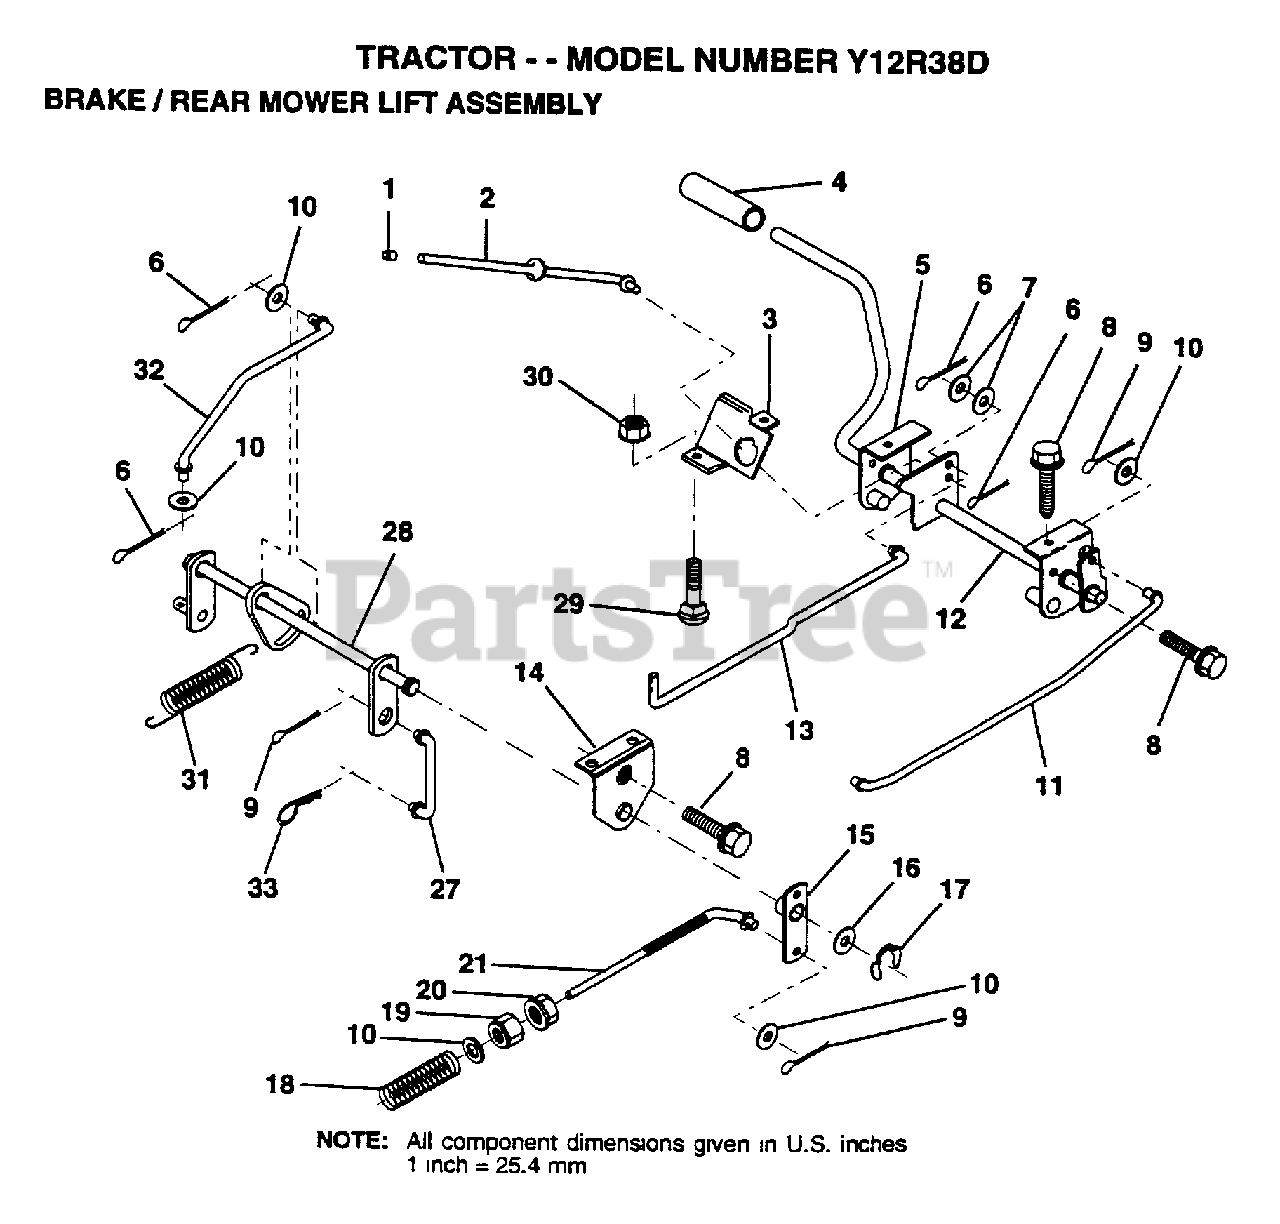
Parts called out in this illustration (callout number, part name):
1	PLUNGER CAP T
2	"ROD,PARK BRAKE"
3	"BRKT,PARK BRAKE"
4	PEDAL COVER T
5	BRK ASM CLUT LH
7	WASHER
8	SCREW LT
9	COTTER PIN
10	WASHER
11	"ROD,FRT BRAKE"
12	PEDAL ASM CLU/BRK
13	"ROD,CLUTCH"
14	"BRKT,LIFT SHAFT"
15	PVT BRAKE ARM ASM
16	WASHER T
17	KLIP RING
18	SPRING ROD LT
20	NUT
27	LINK LIFT REAR LR
28	LIFT.ASM.REAR.LR
31	COUNTER SPRING
32	LINK LIFT LEVER
